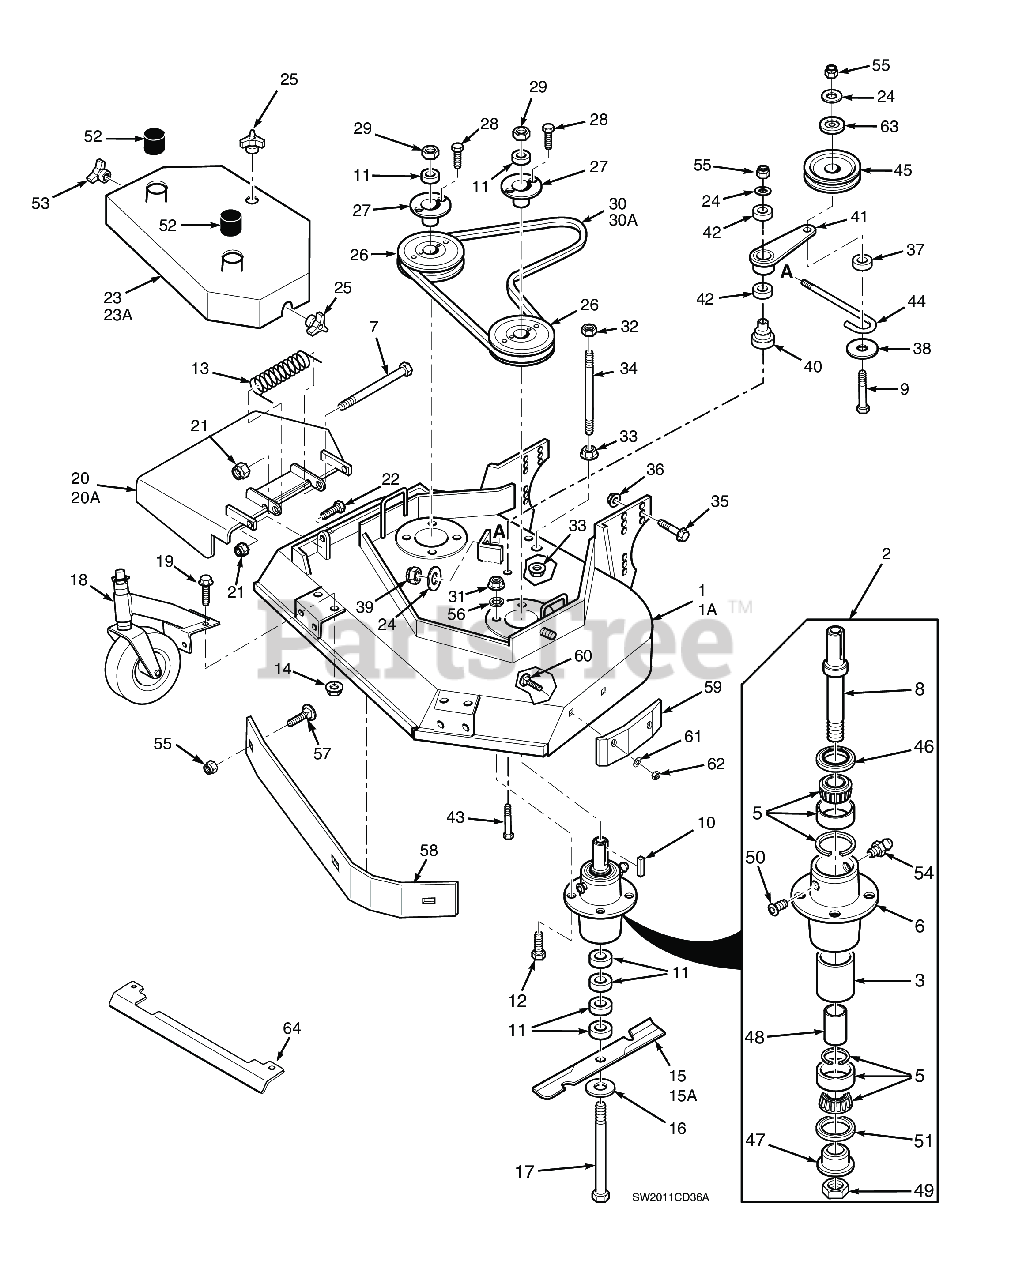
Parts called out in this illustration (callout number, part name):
1	Cutter Deck w/Decals
2	Cutter Spindle Assembly
3	Spacer, Outside, Cutter Spindle
5	Tapered Bearing Set (Two Bearings W/Race)
6	Housing, Spindle
7	Bolt, 5/16-18 x 4-3/4" Hex Head
8	Spindle Shaft, Tapered Brng
9	Capscrew, Hex Head 3/8-16 x 3-3/4"
10	Key, 1/4 x 1/4 x 2.0"
11	Spacer, Cutter Blade - Small
12	Bolt, Hex Head 5/16-18 x 1-1/2" Grade 8
13	Spring, Discharge Chute
14	Nut, Serrated Flange 5/16-18 (Right Front Engine Mounting, Briggs and Kohler Only)
15	Cutter Blade 18" (marbane)
15A	Cutter Blade 18" Hi Lift (marbane)
16	Flatwasher, 5/8-.688 x 1-3/4 x .134 HD
17	BOLT, HEX HEAD, 5/8-11 X 9-1/2 GR.5
18	Caster Assembly
19	Capscrew, 5/16-18 x .75 Serrated Flange Hex Head
20A	Discharge Chute Assembly
20A	Discharge Chute Assy. (CA)
20A	Turbo Baffle
21	HEX NUT, ELASTIC STOP LOCK, 5/16-18
22	Bolt, Heax Head 5/16-18 x 1" (48V / 52V)
23A	Belt Cover Assy (Incl. Decal)
24	Flatwasher, 3/8 (.391 x .938 x .105 HD) Grade 8
25	WINGNUT, PLASTIC 3/8-16 X .875
26	Pulley, 5.75 O.D. (Gasoline Engines)
27	Hub, Tapered 1-1/8" Bore
28	Bolt, Hex Head 1/4-20 x 1" Grade 8 Black
29	Hex Locknut, Elastic Stop, 3/8-16
30A	BELT CUTTER DK SM36
31	Lock Nut, 5/16-18 Elastic Stop Grade 8
32	Bolt, Hex Head 3/8-16 x 1" Ser. Flg.
33	NUT, 3/8-16 SERRATED FLANGE HEX HEAD
34	Bolt, 5/16-18 x 1" Hex Head
35	Serr. Fl. Hex Head Capscrew, 1/2-13 x 1-3/4
36	Nut, Elastic Stop 1/2-13, (STT-52 & STTII-52)
37	SPACER, J-PULL ROD
38	Flatwasher, 3/8 (.375 x 1-1/2" x 16 ga.)
39	HEX NUT, ELASTIC STOP LOCK, 3/8-16
40	Pivot, Idler - Short
41	Idler Arm Assy.
42	BEARINGS, BALL, NEUTRAL RETURN
43	Capscrew, Hex Head 3/8-16 x 3.25"
44	J-Hook, Idler Pulley
45	Idler Pulley, Belt Clutch
46	SEAL, 2.00 O.D. X 1.50 BORE
47	SPINDLE BUSHING, BOTTOM
48	SLEEVE, CUTTER SPINDLE
49	Nut , Spec ial 1 -1/ 1 6 - 1 8
50	RELIEF FITTING, TAPERED BEARING SPINDLE
51	Seal, 2.00" O.D. x 1.625" Bore
53	Wing Nut, 3/8-16 (Small) Top side
54	GREASE FITTING, STR. 1/4-28 SELF TAP.
55	HEX NUT, ELASTIC STOP LOCK, 3/8-16
56	Lockwasher, 5/16 (.317 x .586 x .078) Helical Spring
57	Carriage Bolt, 3/8-16 x 1.0"
58	Baffle, Flange - 36A
59	Pad, Deck Wear
60	Bolt, 5/16-18 x .75 RHSN Carriage
61	Flatwasher, 5/16-.344 x .688 x .065 (48V / 52V)
62	Nut, Center Lock, 5/16-18(32)
63	Quick Pin, 5/16" Dia.
64	Heatshield, 16" Small Frame
